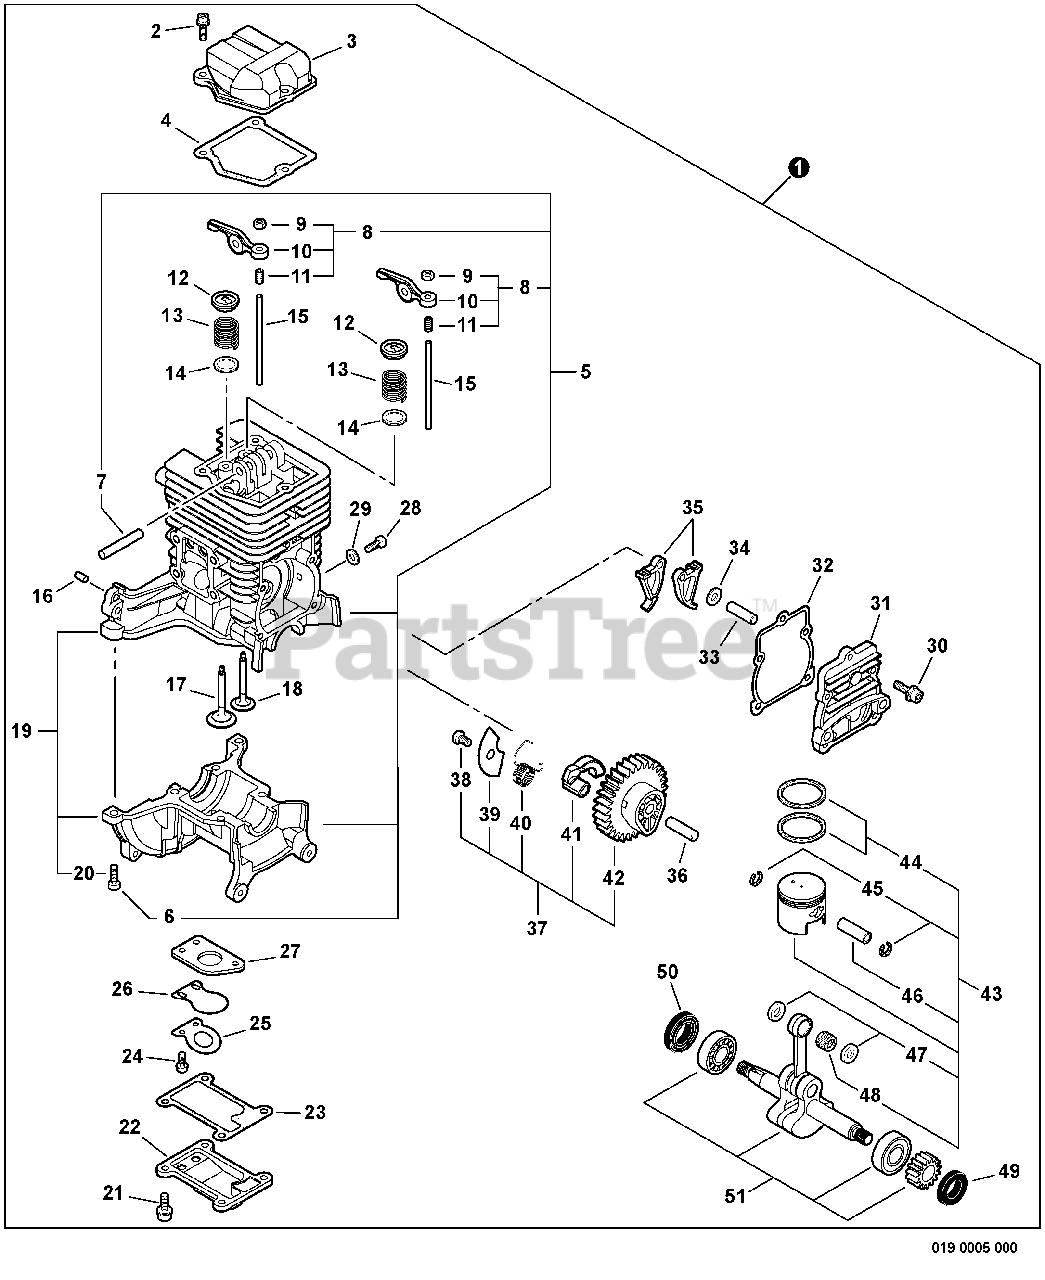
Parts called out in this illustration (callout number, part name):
1	SHORT BLOCK
2	SCREW - 4X14
3	COVER, ROCKER ARM
5	CYLINDER KIT
6	SCREW - 5X16
7	SHAFT, ROCKER ARM
8	ROCKER ARM ASSY
9	LOCKNUT - 5
10	ARM, ROCKER
11	SCREW, ADJUST
12	RETAINER, VALVE
13	SPRING, VALVE
14	WASHER, VALVE - 9
15	PUSHROD
16	PIN - LOCATING
17	VALVE, INTAKE
18	VALVE, EXHAUST
19	CRANKCASE ASSY
20	SCREW - 5X16
21	SCREW - 4X12
22	COVER, REED VALVE
23	GASKET, REED VALVE
24	SCREW - 3X10
25	STOP, REED VALVE
26	VALVE, REED
27	PLATE, REED BACKING
28	SCREW - 5
29	WASHER - 10
30	SCREW - 4X14
31	COVER, CAM GEAR
34	WASHER - 5
35	FOLLOWER, CAM
37	CAM GEAR ASSY
38	SCREW - 4X6 -- TAPPING
39	PLATE, COVER
42	GEAR, CAM
43	PISTON KIT
44	RING, PISTON
45	RING, RETAINING
46	PIN, PISTON
47	SPACER - 9
48	BEARING, NEEDLE
49	SEAL, OIL - 12
50	SEAL, OIL
51	CRANKSHAFT ASSY
